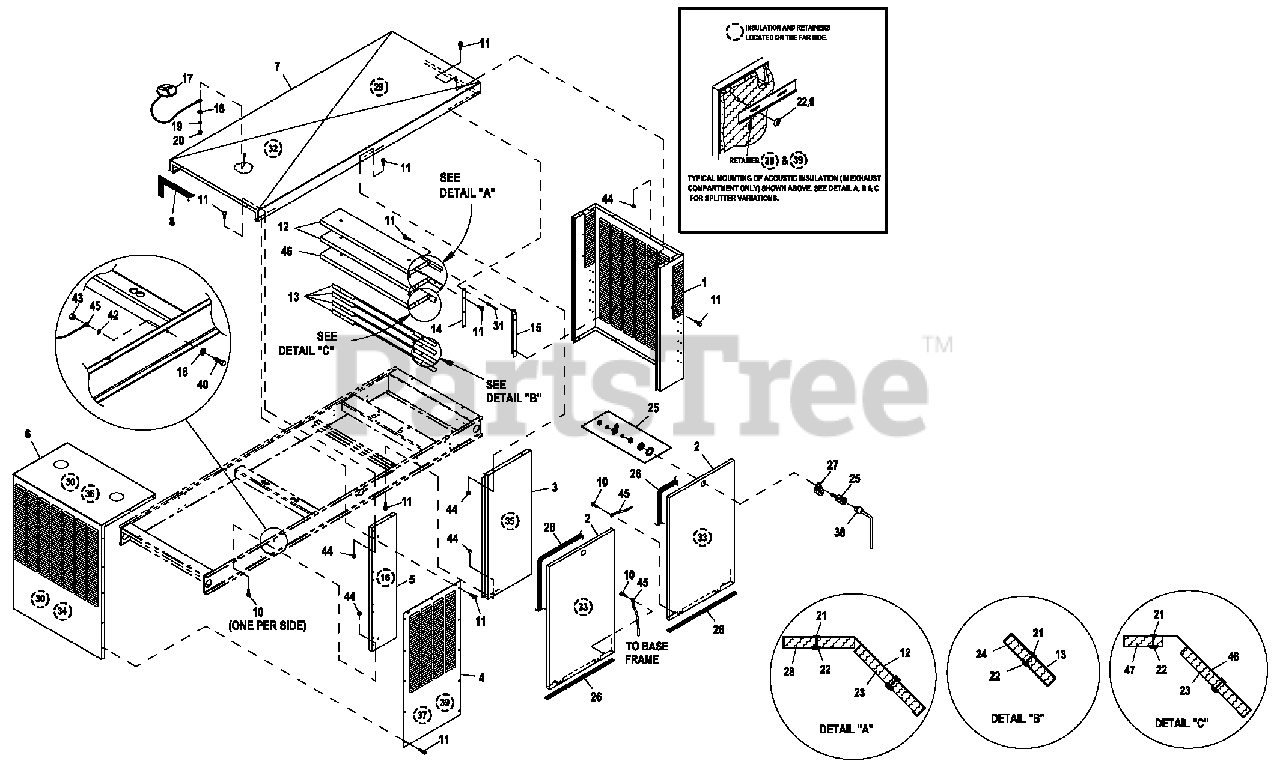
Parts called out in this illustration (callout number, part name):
1	REAR WRAP C5
2	DOOR C5
3	CENTER SUPPORT C5
4	DISCHARGE DUCT LH & RH SIDE C5
5	FRONT CORNERS C5
6	DUCT CENTER DISCHARGE
7	ROOF C5ALUM
8	STRIP SEALANT 1/8X1 (44.5"LG)
9	WASHER SELF LOCKING DO ME #8-32
10	SCREW TH-FR M M 6 W/CAP SHKPRF W
11	SCREW THF M 6-1 X 16 N WA Z/JS
12	SPLITTER
13	SPLITTER SHORT
14	STRINGER SPLITTER C3
15	SUPPORT SPLITTER C5 130KW
16	INSUL CORNER POST
17	ASSY ACCESS COVER
18	WASHER FLAT 1/4-M6 ZINC
19	WASHER LOCK M 6-1/4
20	NUT HEX 1/4-20 STEEL
21	INSULATION RETAINMENT HANGER
22	WASHER SELF LOCKING DO ME #4-40
23	INSUL SPLITTER
24	INSULSHORT LOUVER
25	VISE-ACTION LATCH SLOTTED CIR
26	GASKET EXTRUDED TRIM (566" LG)
27	TAB PULL
28	INSUL SPLITTERS M L
29	INSUL ROOF TOP REAR
30	RETAINER INSULATION (740)
31	RIVET POP.1875 X .450 SS
32	INSUL ROOF TOP FRT
33	INSUL DOOR
34	INSUL DISCHARGE DUCT
35	INSUL CENTER SUPPORT
36	INSUL DISCHARGE DUCT TOP
37	INSUL INNER DUCT SIDE
38	KEY VISE-ACTION LATCH SLOT CIR
39	RETAINER INSULATION (450)
40	SCREW HHC M 6-1.0 X 20 G8.8
42	WASHER SHAKEPROOF INT 1/4
43	NUT HEX M 6 X 1.0 G8 YEL CHR
44	NUT HEX LOCK M6-1.0 SS NY INS
45	ASSY WIRE 14AWG 34.8" GRN/YEL
46	SPLITTER C5
47	INSUL SPLITTER SHRT M PS
